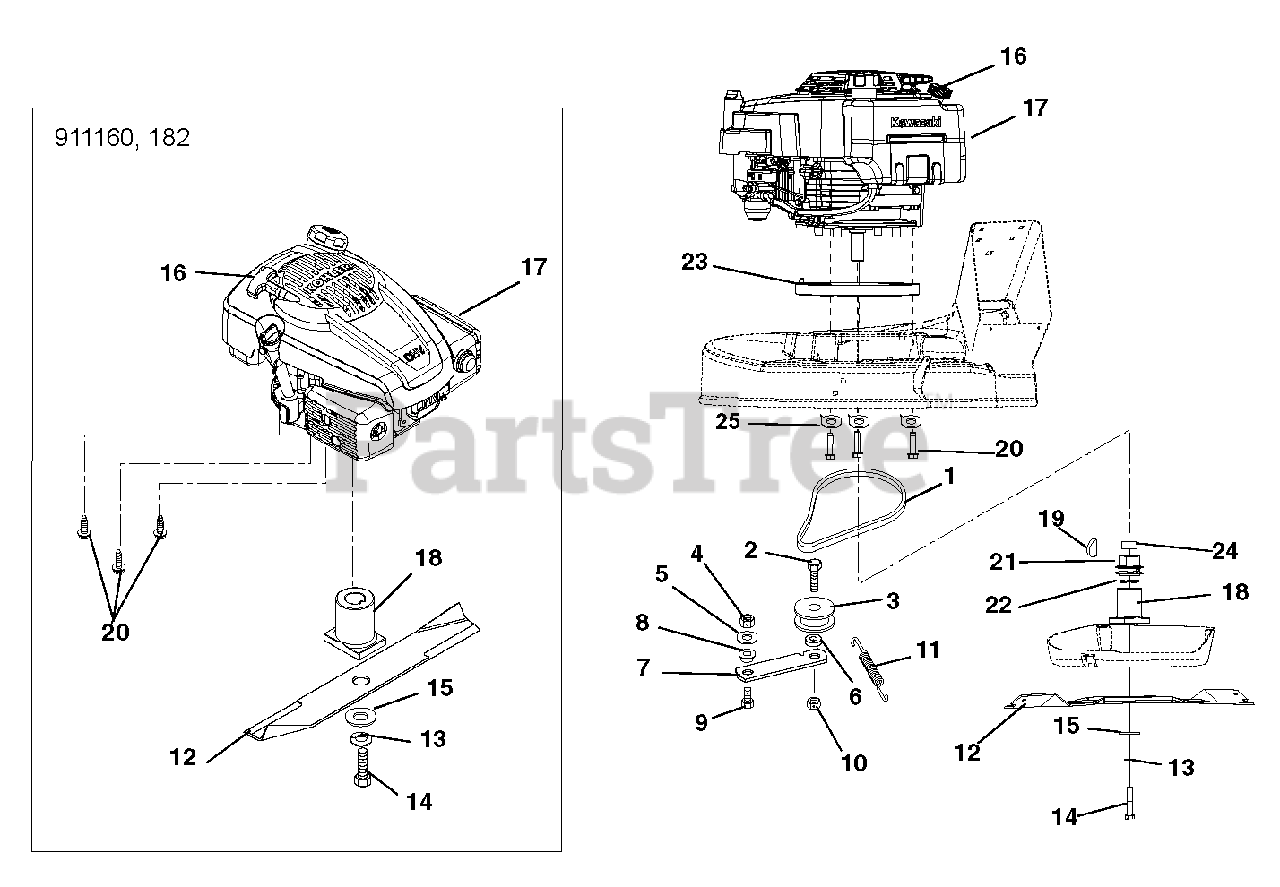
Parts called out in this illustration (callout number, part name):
1	V-Belt 3L Section
2	Bolt, Hex .44-14 x 1.50 Grade 5
3	Idler, Flat 1.75 x .47
4	Nut, Locking Center .31 -18
5	Washer, Flat Steel .344 x .688 x .065
6	Bushing, Sleeve .469 x .75 x .43
7	Idler Arm
8	Bushing, Flange .325 x .501 x .250 x 1.120
9	Bolt, Hex .31-18 x .75 Grade 5
10	Nut, Locking Center .44-14
11	Spring, Tension .043 x .44 x 3.31
12	Blade, 21" Mower
13	Washer, Locking .38 x .094
14	Bolt, Hex .38-24 x 2.00 Grade 8 (911260)
15	Washer, Flat Steel .390 x 1.50 x .125
16	Recoil Start Handle
17	Engine, Kohler XT-7 (911260)
18	Adapter, Blade (911260)
19	Key, Woodruff .156 x .625 x .25 SAE #6 (911186, 187)
20	Screw, Tapping .38-16 x 1.00 Hex Washer Head (911260)
21	Pulley, Crank (911186, 187)
22	Washer, Wave .885 x 1.311 x .125 (911186, 187)
23	Plate, Engine Shim (911186, 187)
24	Spacer, .875 x 1.125 x .525 (911186, 187)
25	Spacer, .75 x .515 x .120 (911186, 187)
